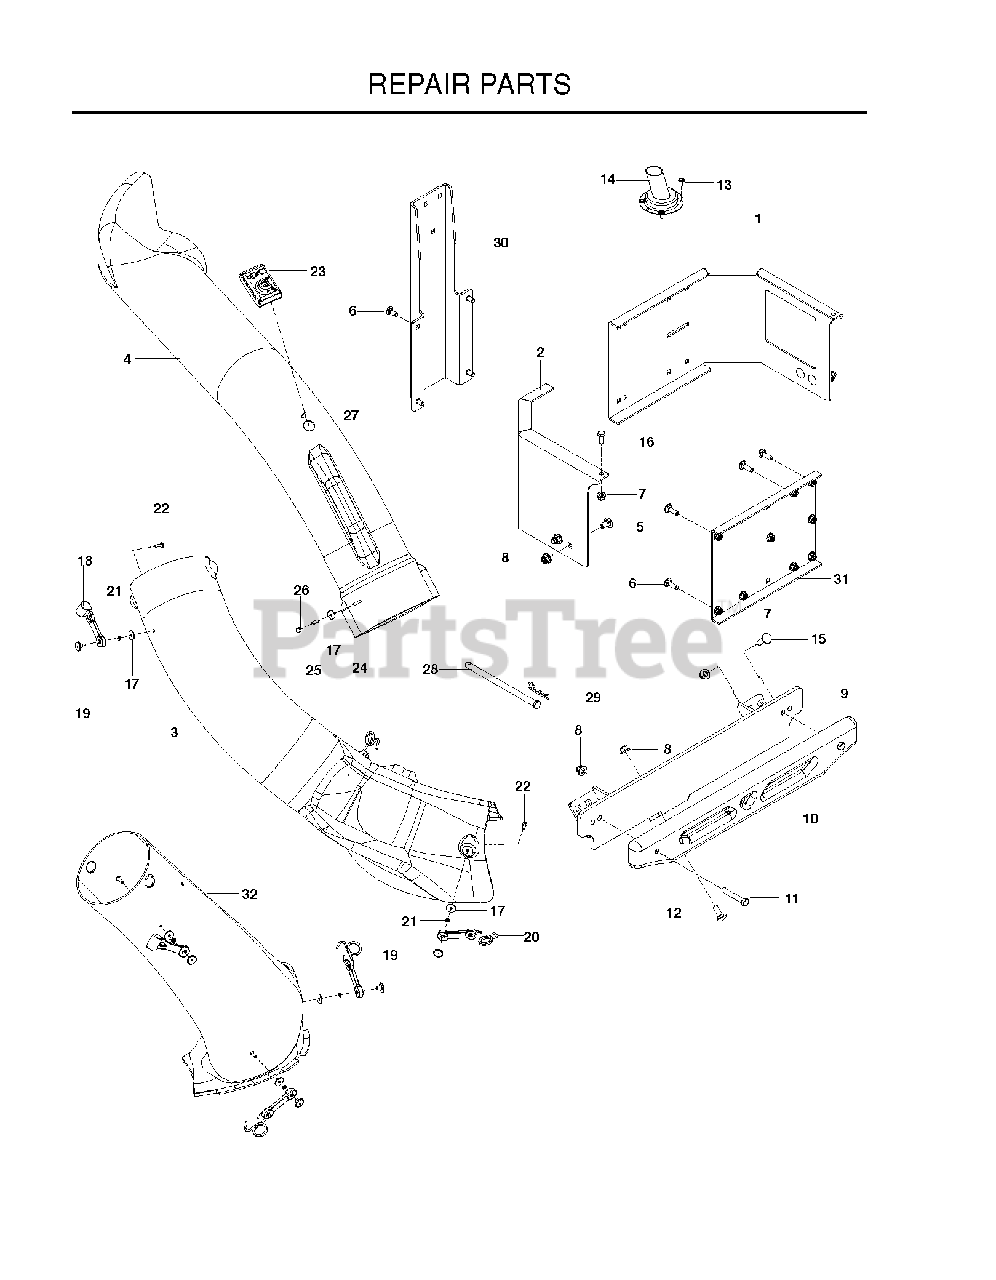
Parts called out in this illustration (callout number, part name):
1	GUARD, REAR LEFT, BLK
2	GUARD, REAR RIGHT, BLK
3	CHUTE, LOWER 30
4	CHUTE.COLLECTION.UPPER
5	RHSNB 3/8-16 X 3/4 GR5 ZD
6	RHSNB 5/16C X 1
7	5/16-18 NYLOC FLANGE NUT
8	NUT 3/8-16 HEX FLG NYLOC ZD
9	WELDMENT.WEIGHT.BRACKET.RZ30.B
10	WEIGHT.CAST
11	HCS 3/8C X 2 1/4
12	RHSNB 3/8C X 1
13	SCREW, TAP #10-16 X 1/2
14	MUFFLER EXTENSION
15	RHSNB 3/8-16 X 1-1/4
16	SCREW 5/16C X 1 HEX CAP
18	HOOD LATCH
19	NUT 10-24 WELD PLATED
20	LATCH ASSY TBR
21	WASHER - 3/16 LOCK ZD
22	SCREW #10-24 X 5/8
23	DUMP BAG INDICATOR
24	SCREW #10-24 X 1-1/8 ZD SPEC
25	BSHG .202X.75 LG SPLIT ZD SPEC
26	NUT 10-24 ACORN ZD
27	SCREW
28	PIN-CLEVIS 5/16 DIA X 5.19 ZD
29	HAIRPIN #2
30	BRACKET, COLLECTION (PTD)
31	PLATE, REAR SUPPORT, BLK
32	BOOT.LOWER.42
